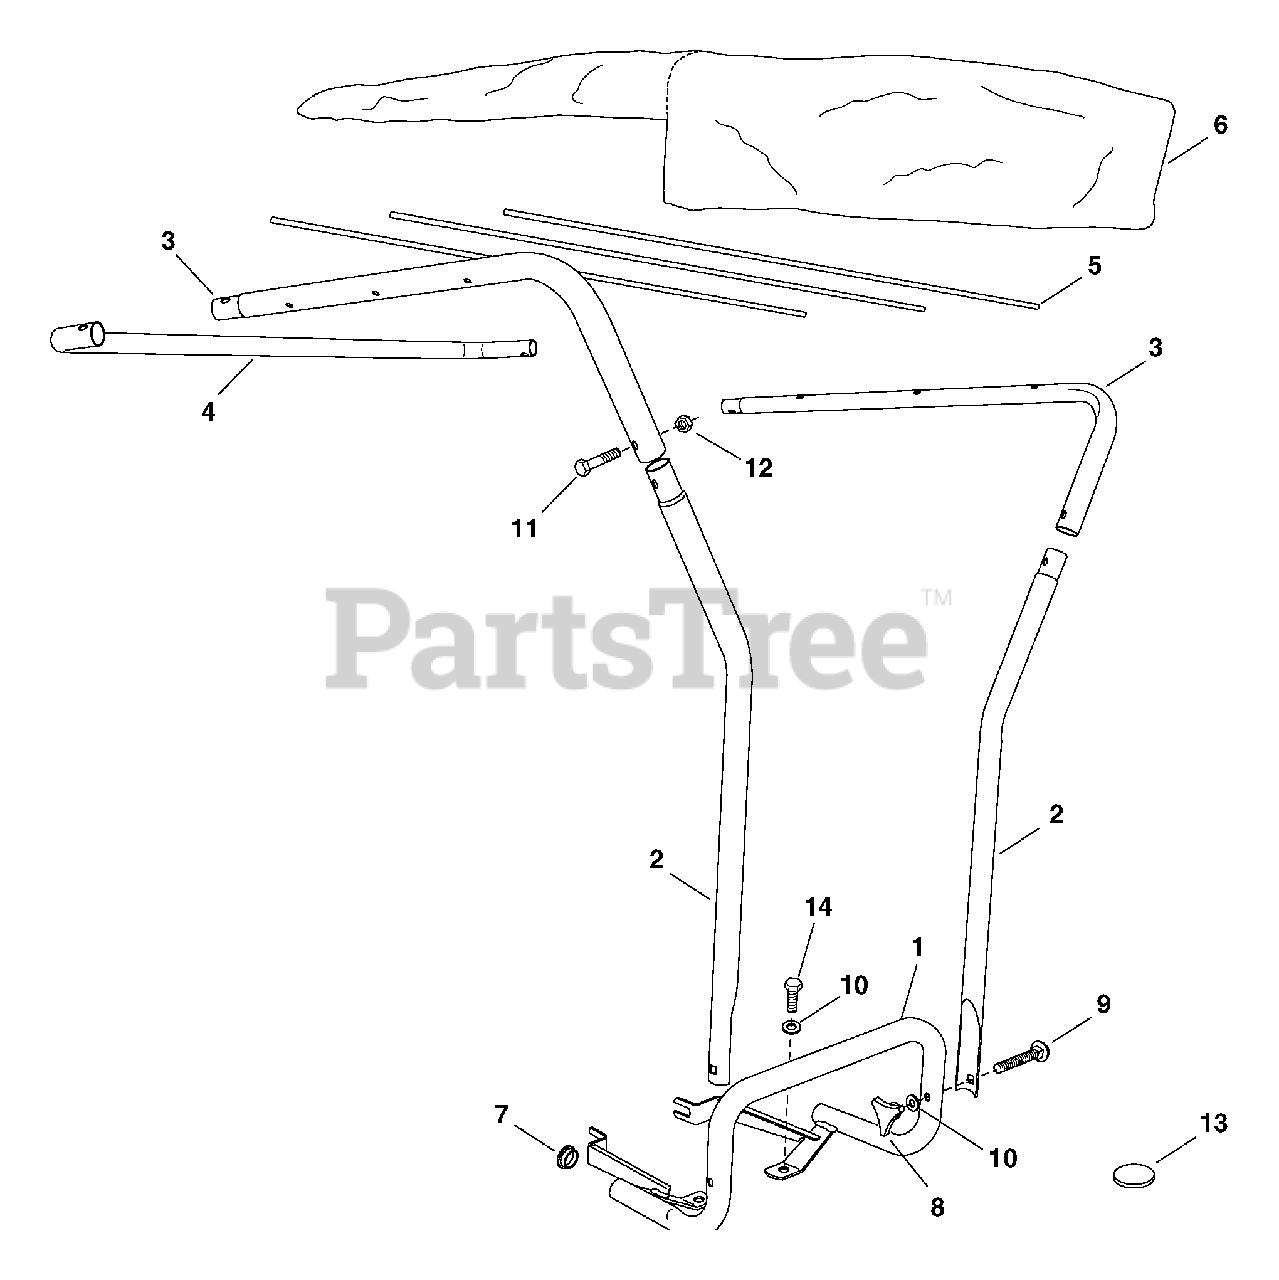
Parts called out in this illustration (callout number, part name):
1	Base Assembly
2	Upright Tube
3	Top Tube
5	Support Rod
6	Vinyl Canopy
7	Plastic Plug
8	Plastic Knob
9	Carriage Bolt, 5/16-18 x 2"
10	Flat Washer, 5/16"
11	Hex Bolt, 1/4-20 x 1-1/2"
12	Hex Lock Nut, 1/4-20
13	Adhesive Pad
14	Hex Bolt, 5/16-18 x 1"
